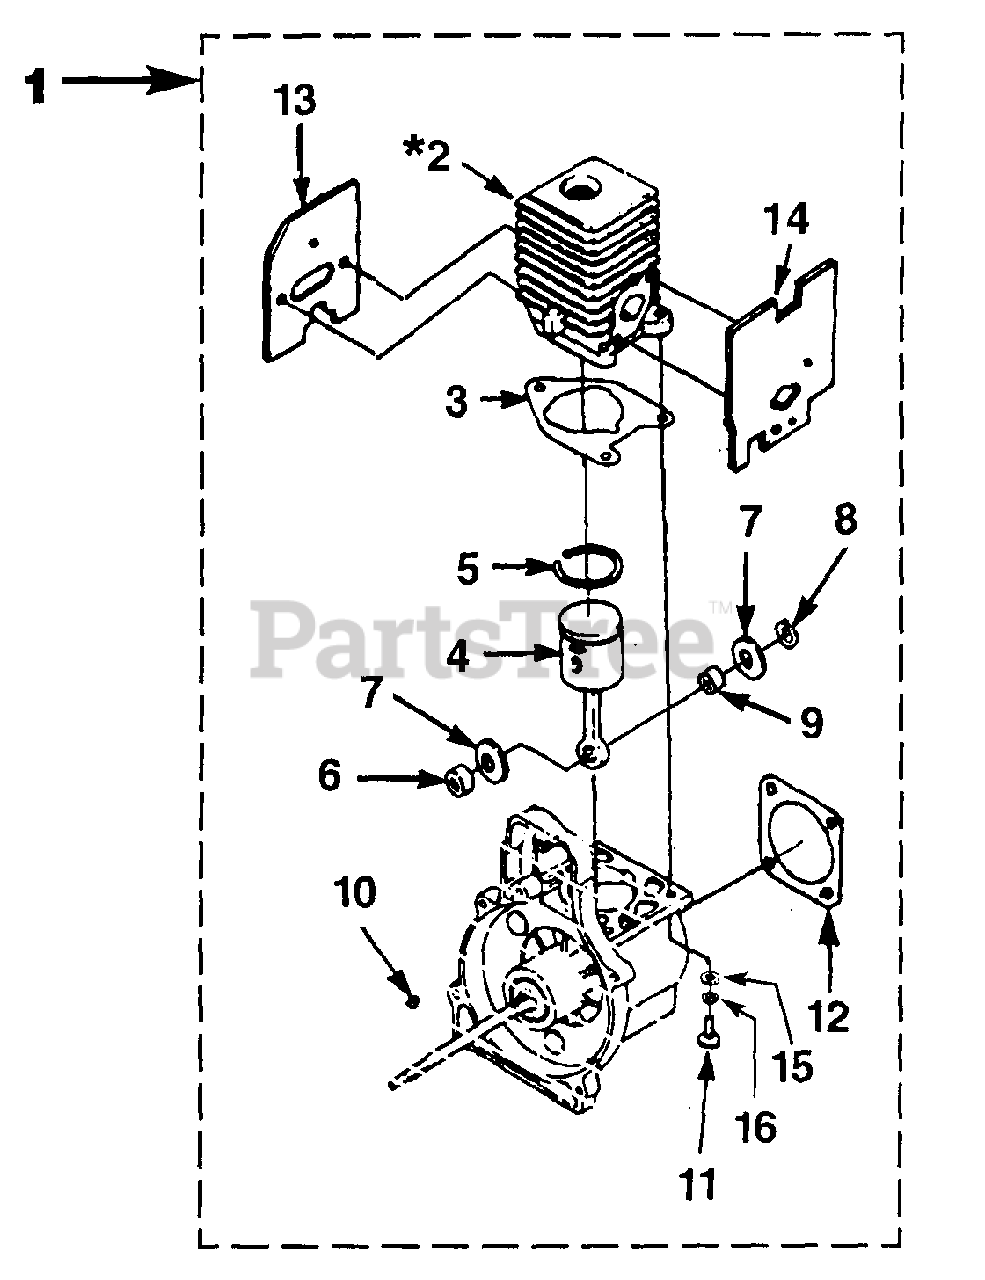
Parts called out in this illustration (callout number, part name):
1	SHORT BLOCK
2	CYLINDER & GASKET
3	GASKET-Cylinder
4	PISTON & ROD
5	RING-Piston
6	SPACER-Bearing
7	WASHER-Thrust
8	RING-Retaining
9	BEARING-Needle
10	KEY-Woodruff
11	SCREW-Torx Pan Hd. (12-24 x 3/4")
12	GASKET-Crankcase
13	GASKET-Muffler
14	GASKET-Heat Dam
15	WASHER, Flat
16	WASHER, Lock
